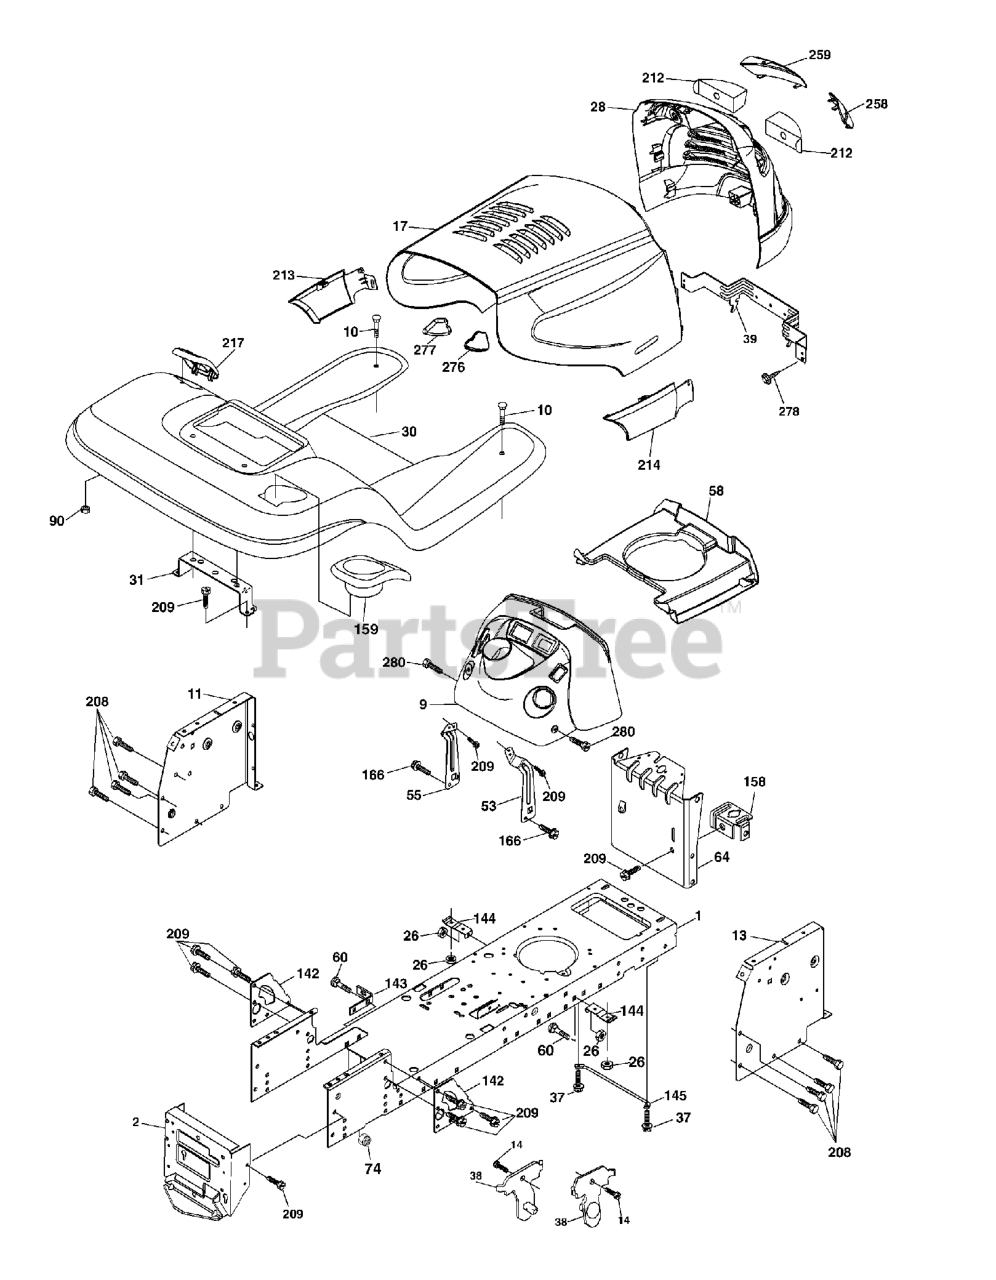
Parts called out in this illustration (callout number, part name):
1	CHASSIS STAMPING
2	DRAWBAR, 12GA
9	DASH.NON-TEX.GRAY
10	BOLT D
11	PANEL.DASH.LH.LTX
13	PANEL DASH RH
14	SCREW LT
17	HOOD
26	NUT
28	GRILL/LENS ASSY ( YT MODEL)
30	FENDER STL W/CUPHOLDER
31	BRACKET.SUPPORT.FENDER
37	Screw 5/16-18 x 1/2 Hex, Self Tapping 5/16-18 x 1/2
38	BRACKET.ASM.PIVOT.MOWER.REAR
39	BRACKET PIVOT LASER
53	BRACKET DASH RH
55	BRACKET DASH LH
58	AIR DUCT ENGINE
60	Bolt - Rd. Hd. Sq. Neckiage 3/8 16 x 3/4
64	DASH LOWER
74	LOCKNUT
90	NUT.PUSH.3/16
142	PLATE REINFORCEMENT
143	BRACKET, SWAYBAR CHASSIS
144	BRKT, FOOT REST
145	ROD PIVOT CHASSIS/HOOD
158	BRACKET PARKING BRAKE
159	GREY CUP HOLDER
166	SCREW
208	SCREW 3/8-16X1/2
209	SCREW, 3/8-16X3/4
212	INSERT LENS
213	SKIRT SIDE LH
214	SKIRT SIDE RH
217	CONSOLE FUEL WINDOW
258	LENS ELITE CLEAR RH
259	LENS ELITE CLEAR LH
276	BUMPER HOOD RH
277	BUMPER HOOD LH
278	SCREW
280	SCREW THDROL 3/8-16 X 1-1/2
